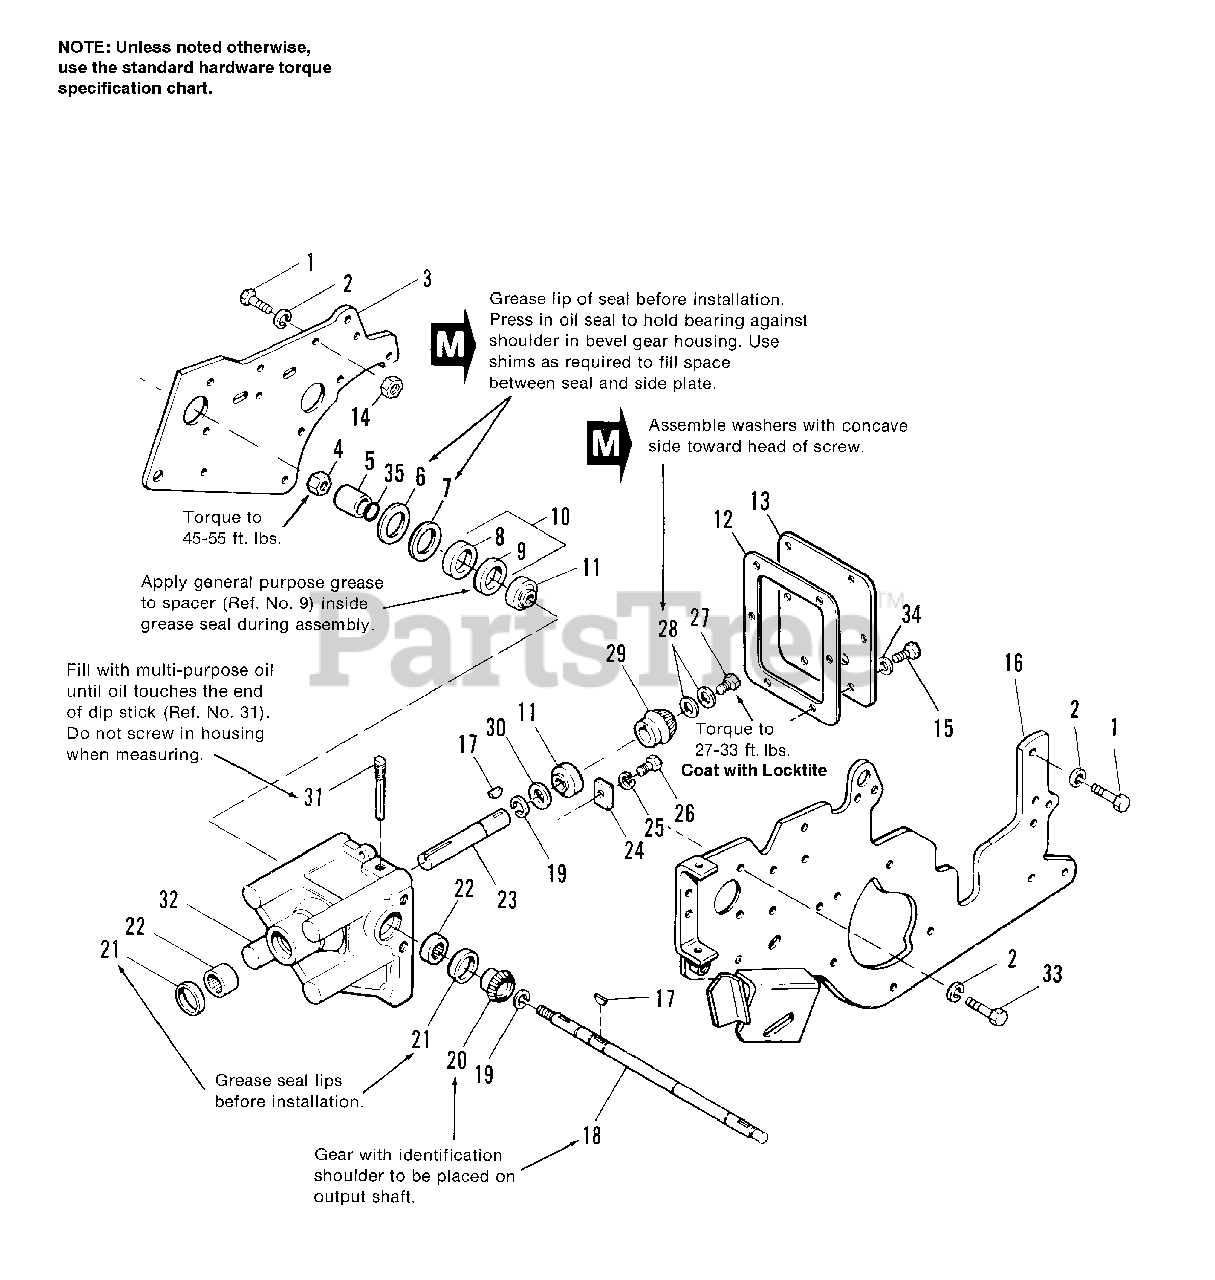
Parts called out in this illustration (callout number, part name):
1	CAPSCREW, Hex Hd, 7/16-14 x 1-1/4
2	LOCKWASHER, 7/16
3	PLATE, Side, R.H.
4	LOCKNUT, Hex, Jam, 3/4-16
8	REPAIR KIT, Seal
9	SPACER, Seal, Oil
10	REPAIR KIT, Seal
11	BEARING, Ball
14	NUT, Hex, 7/16-14 x 1
15	CAPSCREW, Hex Hd, 1/4-20 x 5/8
16	PLATE ASSEMBLY, Side, L.H.
17	KEY, Woodruff, #9
18	SHAFT, Driven
19	RING, Retaining
20	GEAR, Bevel, Driven
22	BEARING, Needle
23	SHAFT, Driver
24	PLATE, Bearing, Clamp
25	LOCKWASHER, 5/16
26	CAPSCREW, Hex Hd, 5/16-18 x 5/8
27	CAPSCREW, Hex Hd, 5/16-18 x 3/4
29	GEAR, Bevel, Driver
31	PLUG ASSEMBLY
32	HOUSING, Bevel Gear
33	CAPSCREW, Hex Hd, 7/16-14 x 1
34	LOCKWASHER, 1/4, I.D.
